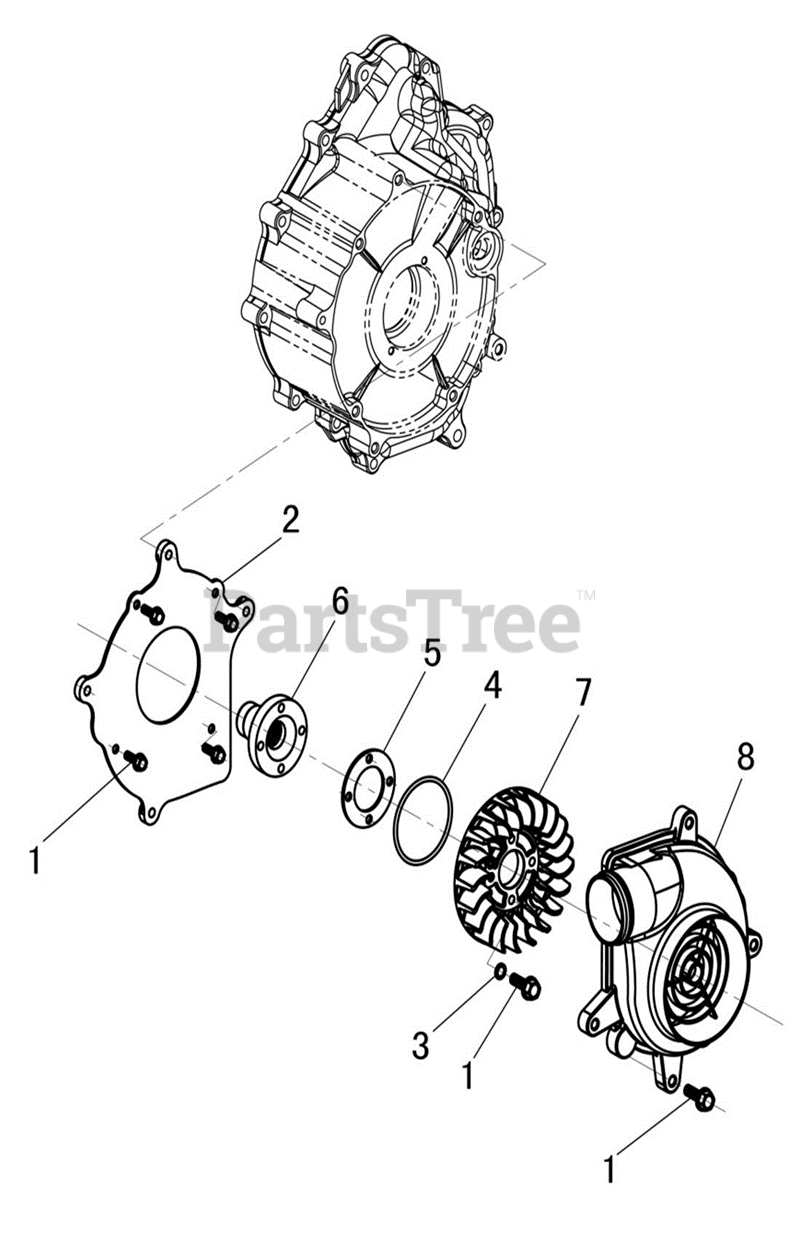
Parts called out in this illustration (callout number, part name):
1	HEX FLANGE BOLTS M6X20
2	BASE PLATE
3	WASHER 6X11X1.5
4	O-RING 64.4X3.1
5	FAN STRONGBACK
8	FAN COWL
